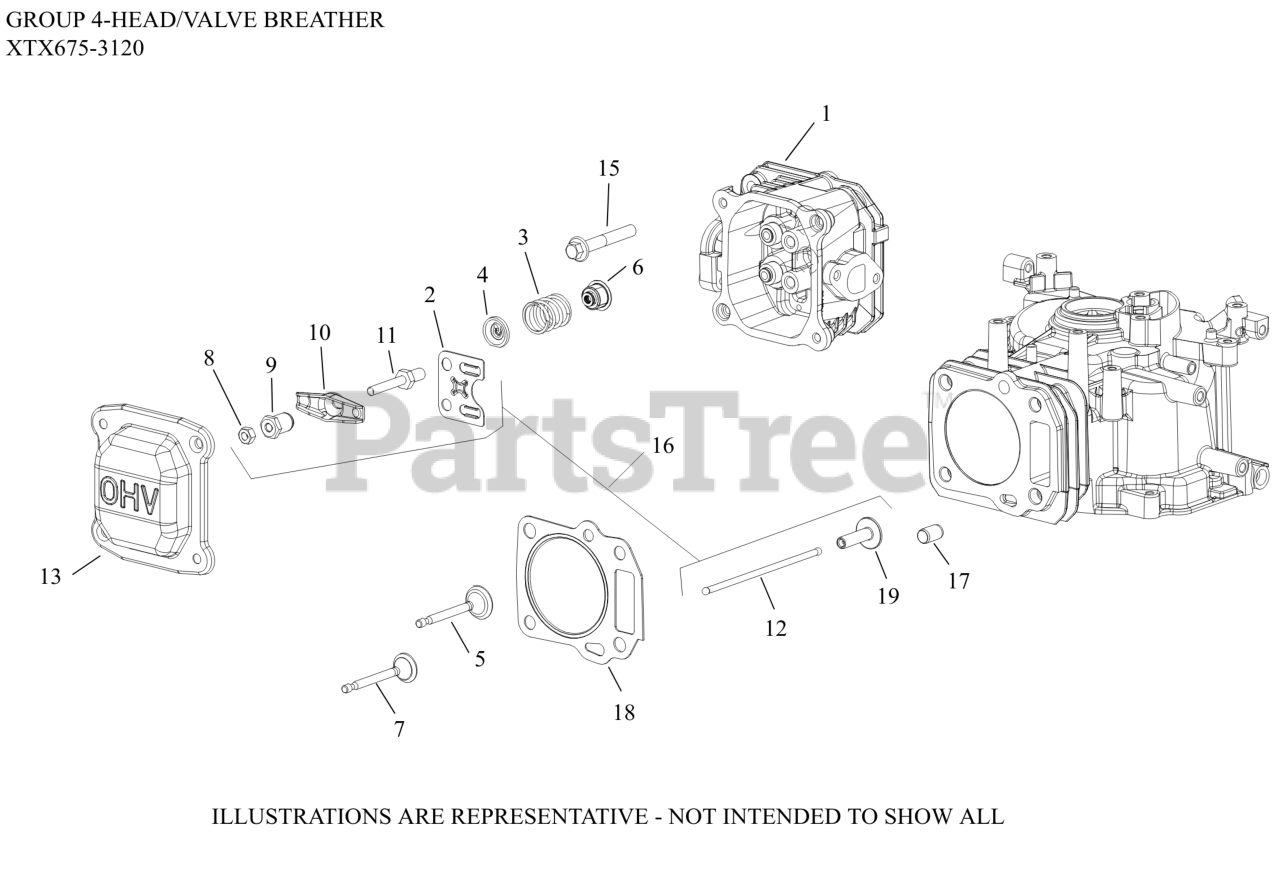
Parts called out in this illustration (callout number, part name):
1	HEAD, CYLINDER
2	PLATE, PUSHROD GUIDE
3	SPRING, VALVE
4	RETAINER, VALVE SPRING
5	VALVE INTAKE
6	SEAL, VALVE STEM
7	VALVE, EXHAUST
8	NUT, HEX JAM
9	PIVOT, ROCKER ARM
10	ARM, ROCKER
11	STUD, ROCKER ARM-USE 14 072 22-S
12	ROD, PUSH
13	COVER, VALVE
15	SCREW, HEX FLANGE M8
16	KIT, VALVE TRAIN
17	DOWEL, CYLINDER HEAD
18	KIT HEAD GASKET
19	LIFTER, VALVE
